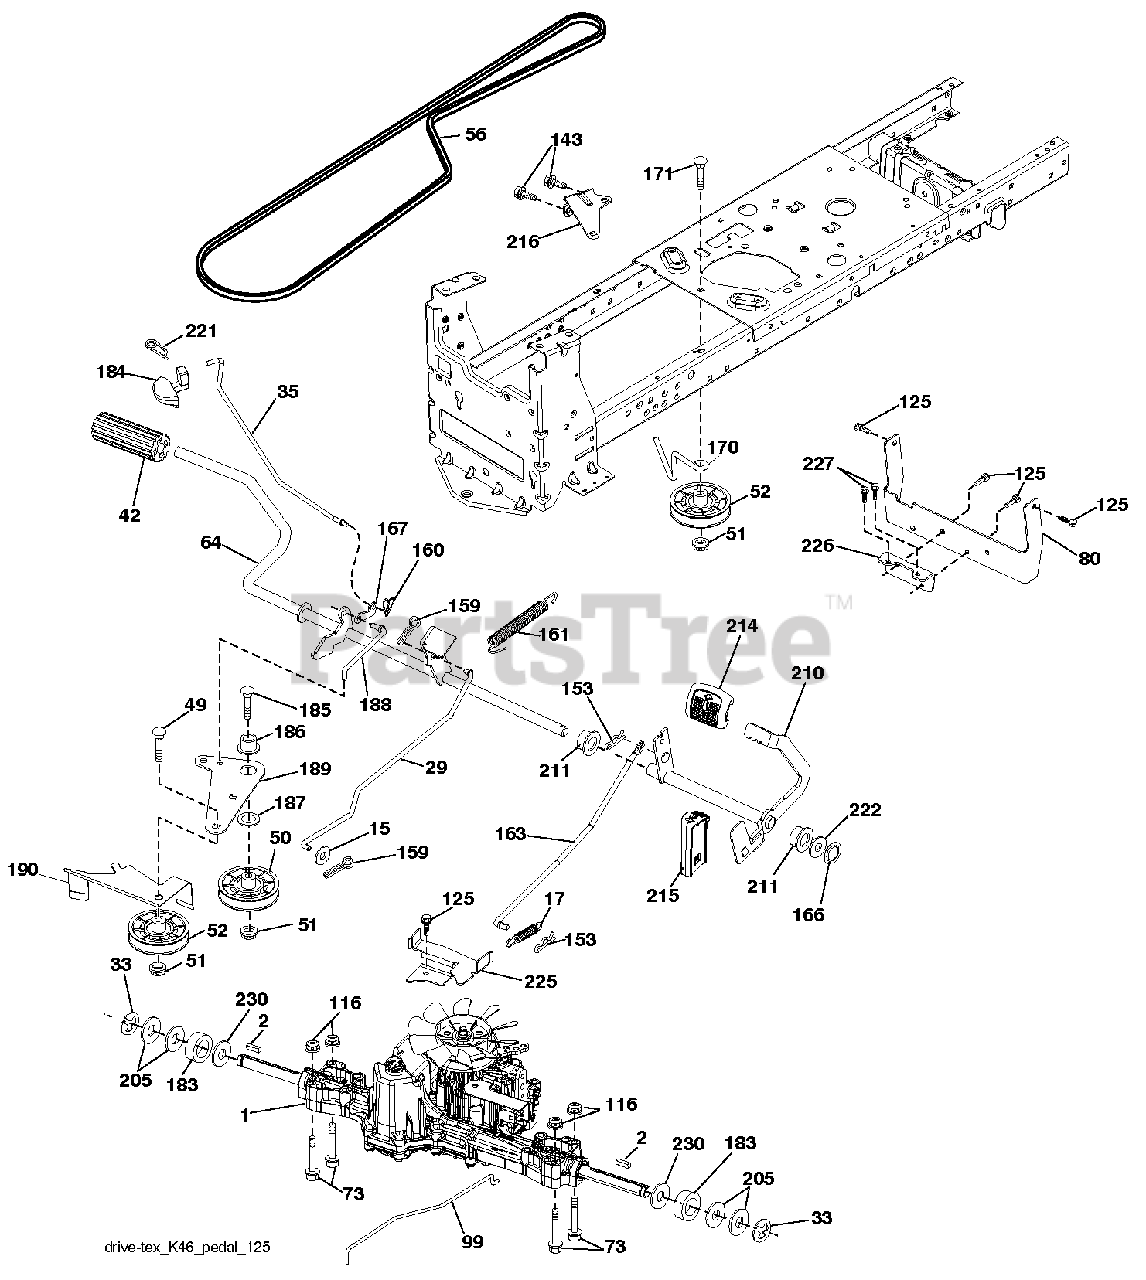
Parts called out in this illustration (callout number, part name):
2	SQUARE KEY
15	WASHER
17	SPRING.BRAKE.K46.GREEN
29	ROD.BRAKE.K46
33	E-RING LT
50	IDLER.FLAT.910.OFFSET
52	IDLER.V-GROOVE.910.OFFSET
64	SHAFT.ASM.PEDAL.BRK.CNTR
80	STRAP.TORQUE.K46.K57R.TT
99	ROD.SPRING.BYPASS.K46.LT.Z
116	NUT LOCK HEX FLANGE 5/16-18
143	SCREW LT
159	COTTER PIN
160	RETAINER CLIP
161	SPRING, RETURN LT
166	NUT.PUSH.625
167	LATCH.BRAKE.SPRING
170	KEEPER.V-IDLER.CENTER.
183	SPACER AXLE
186	SPACER.RETAINER
188	LINK.CLUTCH.GROUND.DRIVE
189	BELLCRANK.GROUND.DRIVE.TEX.
190	KEEPER.BELLCRANK.DRIVE
210	ROCKER.ASM.PEDAL.CONTR
211	BEARING.NYLON
214	PAD PEDAL FORWARD
215	PEDAL.REVERSE.TEX.GT.4
216	BRACKET.PULLEY.IDLER.W/TEX
221	RETAINER.SPRING.CLIP.H
222	WASHER 21/32 X 1-1/4 X 10 GA.
225	KEEPER.BELT.TRANSAXLE.K46
226	BRACKET.MOUNT.TORQUE.K46.TLT
230	WASHER.HARDENED
